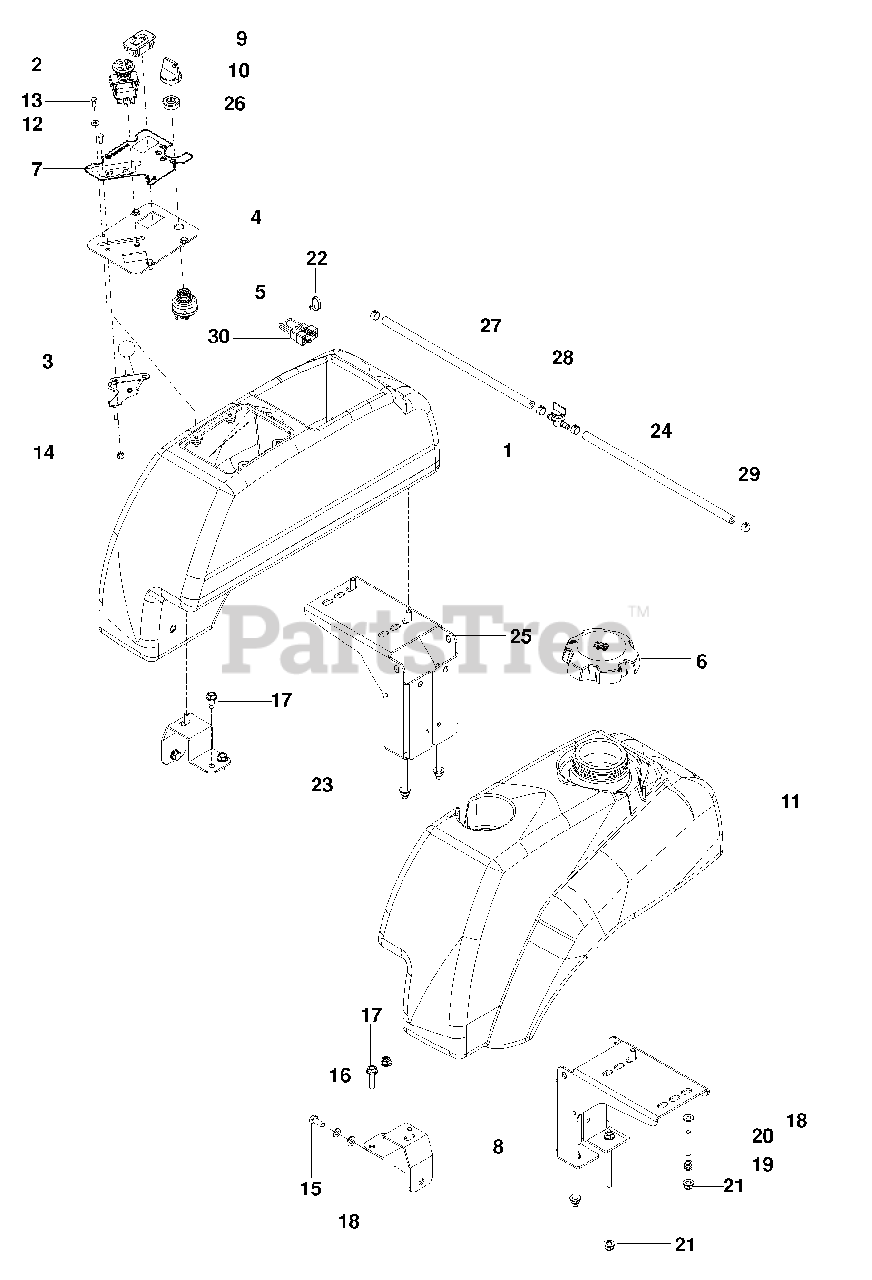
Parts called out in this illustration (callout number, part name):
2	SWITCH, PTO 10 AMP
3	CABLE, THROTTLE
4	CONSOLE PLATE
5	SWITCH, IGNITION
7	DECAL, CONSOLE
8	SUPPORT, TANK
9	HOUR METER
10	KEY, IGNITION
11	TANK, FUEL
12	WASHER #10 FLAT
13	SCREW #10-24 x 1/2 SLT HEX
14	NUT #10-24 HEX NYLOC
15	BOLT, HEX 5/16-18 x 3/4
16	WASHER 5/16 SLW
17	BOLT 5/16-18 x 1, THD FRM
18	WASHER 5/16 SAE FLAT
21	NUT 5/16-18 FLANGE NYLOC
22	TIE, PLASTIC
23	HHFS 5/16-18 x 3 3/4
24	FUEL LINE 18"
25	MOUNT, TANK
26	CAP, IGNITION SWITCH
27	FUEL LINE 13"
28	VALVE, FUEL
29	CLAMP, HOSE
30	PLUG, TIMER
